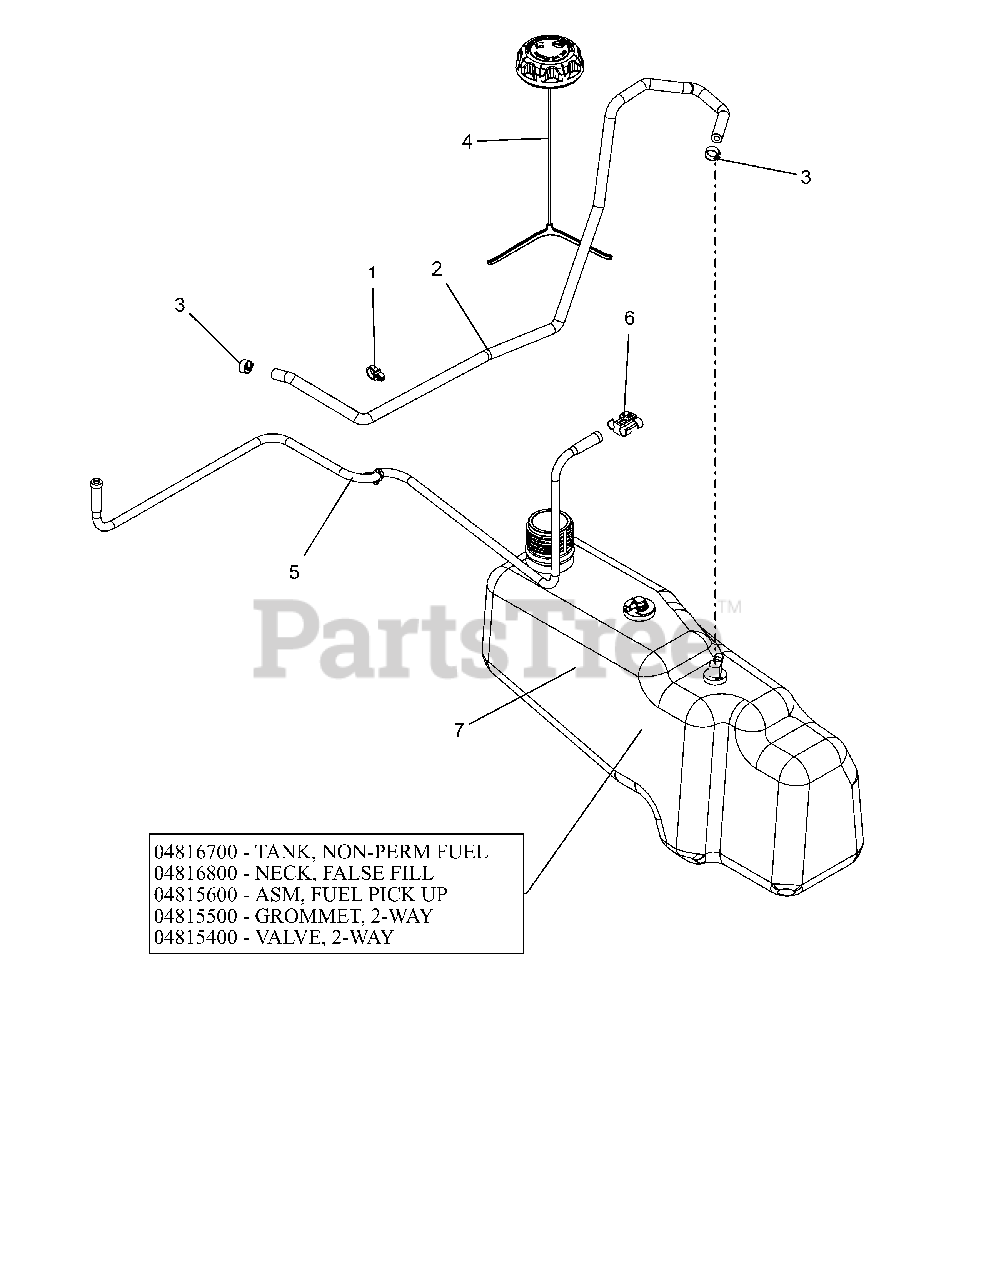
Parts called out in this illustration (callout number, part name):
1	ROUTING CLIP (1/2" ID)
2	HOSE, .25 LOW-PERM BULK GAS
3	CLAMP, FUEL LINE
4	CAP, FUEL VENT-IN 2.25" RATCH.
5	LINE, FUEL VENT KOHLER SMCHOKE
6	CLIP, T, .38-.50
7	ASM,TANK NON-PERM FUEL
7	TANK, ZOOM/ZT NON-PERM, FUEL
7	NECK, FALSE FILL ZOOM/ZT
7	ASM, FUEL PICK-UP ZOOM/ZT 2015
7	GROMMET, 2-WAY
7	VALVE, 2-WAY
